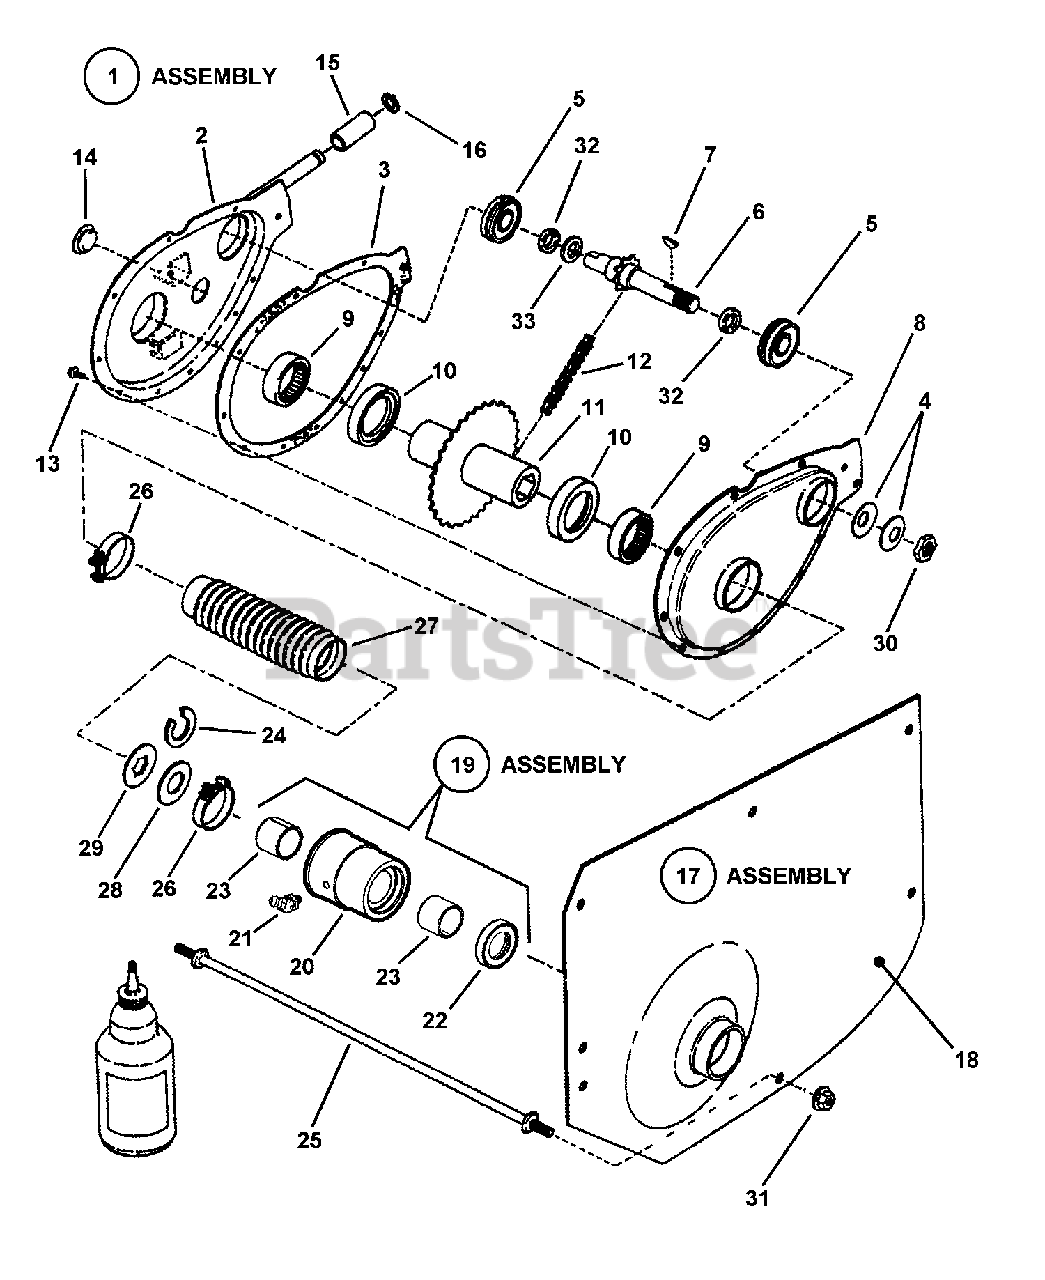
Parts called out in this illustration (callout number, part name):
1	ASSEMBLY, Primary Chain Case
2	WELDMENT, Primary Chain Case, Right Hand
3	GASKET, Primary Chain Case
4	WASHER, 5/8" Belleville
5	BEARING, .625 x 1.37 x .435
6	WELDMENT, Sprocket & Shaft
7	KEY,#5 Woodruff
8	CHAIN CASE HALF, Primary
9	BEARING, Needle 1.355" ID x 1.6245" OD x .5" Wide
10	THRUST WASHER, Nylon
11	WELDMENT, Hub & Sprocket
12	CHAIN, 46 Pitch (#35 Endless)
13	SCREW, #10-24 x 1/2" Hex Washer Self-Tap (Torx)
14	PLUG, 3/4"
15	ROLLER, 1-3/8 Long
16	RING, 1/2" External Retaining (Heavy Duty)
17	ASSEMBLY, Left Hand Fender (Incl. items 18 & 19)
18	FENDER, Left Hand (1.628" I. D. Hole)
19	ASSEMBLY, Axle Bearing (Incl. items 20 thru 23)
20	BEARING, Left Hand Fender, 3/4"
21	FITTING, Lube, 45 Degree, 3/16" w/Hex
22	SEAL, Dust/Grease Axle
23	BEARING, 3/4" I.D. DX
24	WASHER, Shim
25	TIE ROD (5/16-24 thread- both ends)
26	BOOT CLAMP (for 2" Hose)
27	BOOT, Rear Axle, Thick Flange
28	THRUST WASHER (Nylon)
29	WASHER, Thrust
30	NUT, 5/8-18 Hex Nyloc
31	NUT, 5/16-24 Flange Lock (Large)
32	O-RING, 1/2 x 5/8"
33	WASHER, Shim .625 x .875
